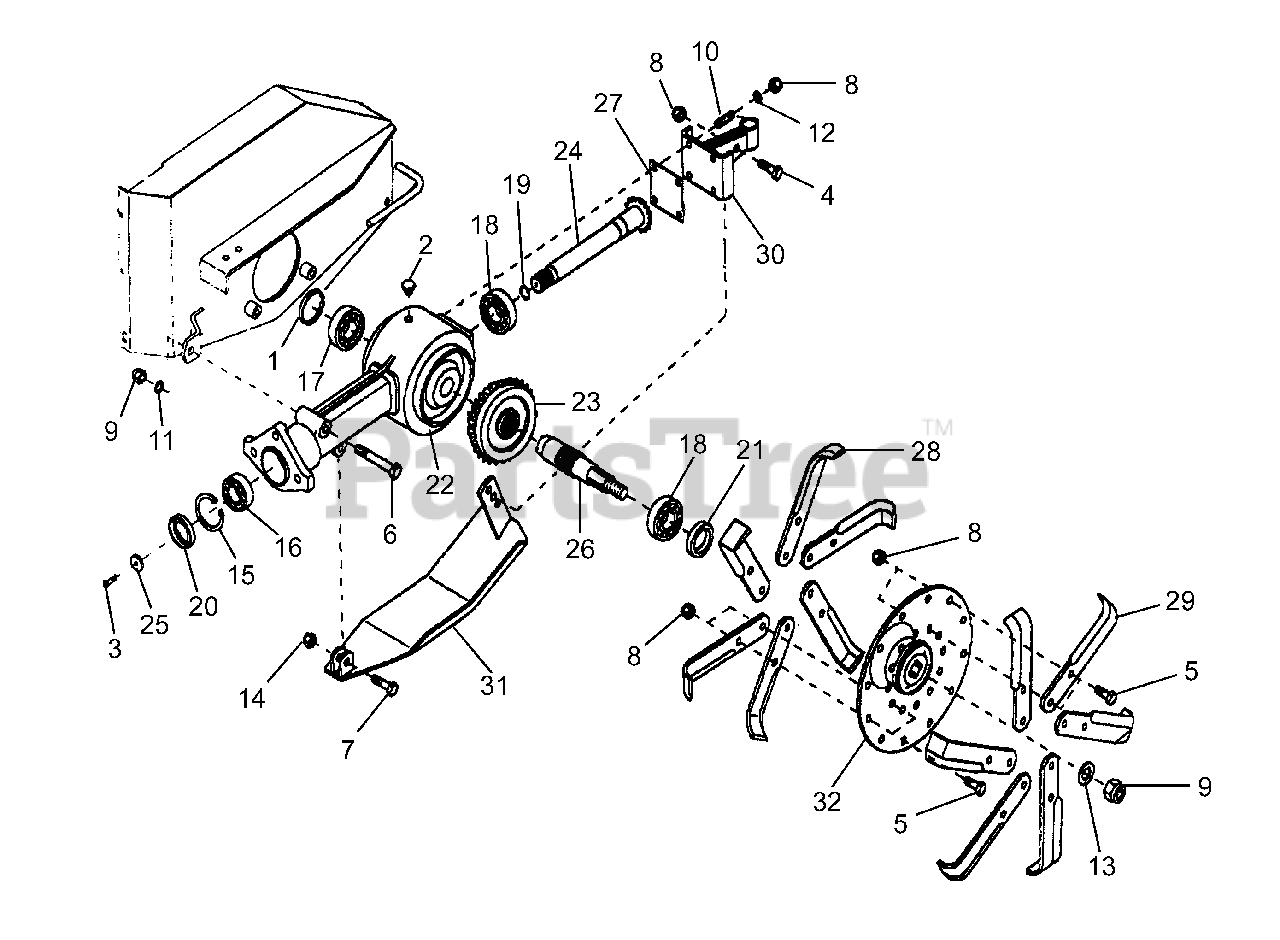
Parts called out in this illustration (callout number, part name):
2	PLUG 1/4 GAS UNI 364
3	HEX SCREW M6X20 UNI 5739 8G
4	HEX. SCREW M10X30 UNI 5739-8G
5	HEX. SCREW M10X25 UNI 5739-8G
6	HEX SCREW M12X80 UNI 5737 8G
7	BOLT
8	SELF-LOCKING NUT
9	SELF-LOCKING NUT M12
10	STUD M10X37X19X15 8G
11	WASHER P.13X24 UNI 6592
12	TOP WASHER 10
13	TOP WASHER 18
14	LOCK NUT
15	INSIDE SEEGER D 52 DIN 472
16	BEARING SKF 25X52X15 6205
18	BEARING 30X62X16
19	OR 4075 18.64X3.53
20	OIL SEAL
21	OIL SEAL 30X52X10 NORMAL
22	CENTRE CULTIVATOR CASING
23	GEAR/CROWN
24	SHAFT
25	WASHER 7X25X4
26	SHAFT
28	LH KNIFE
29	RH KNIFE
31	SKID PLATE
32	DISC/TINE MOUNTING
